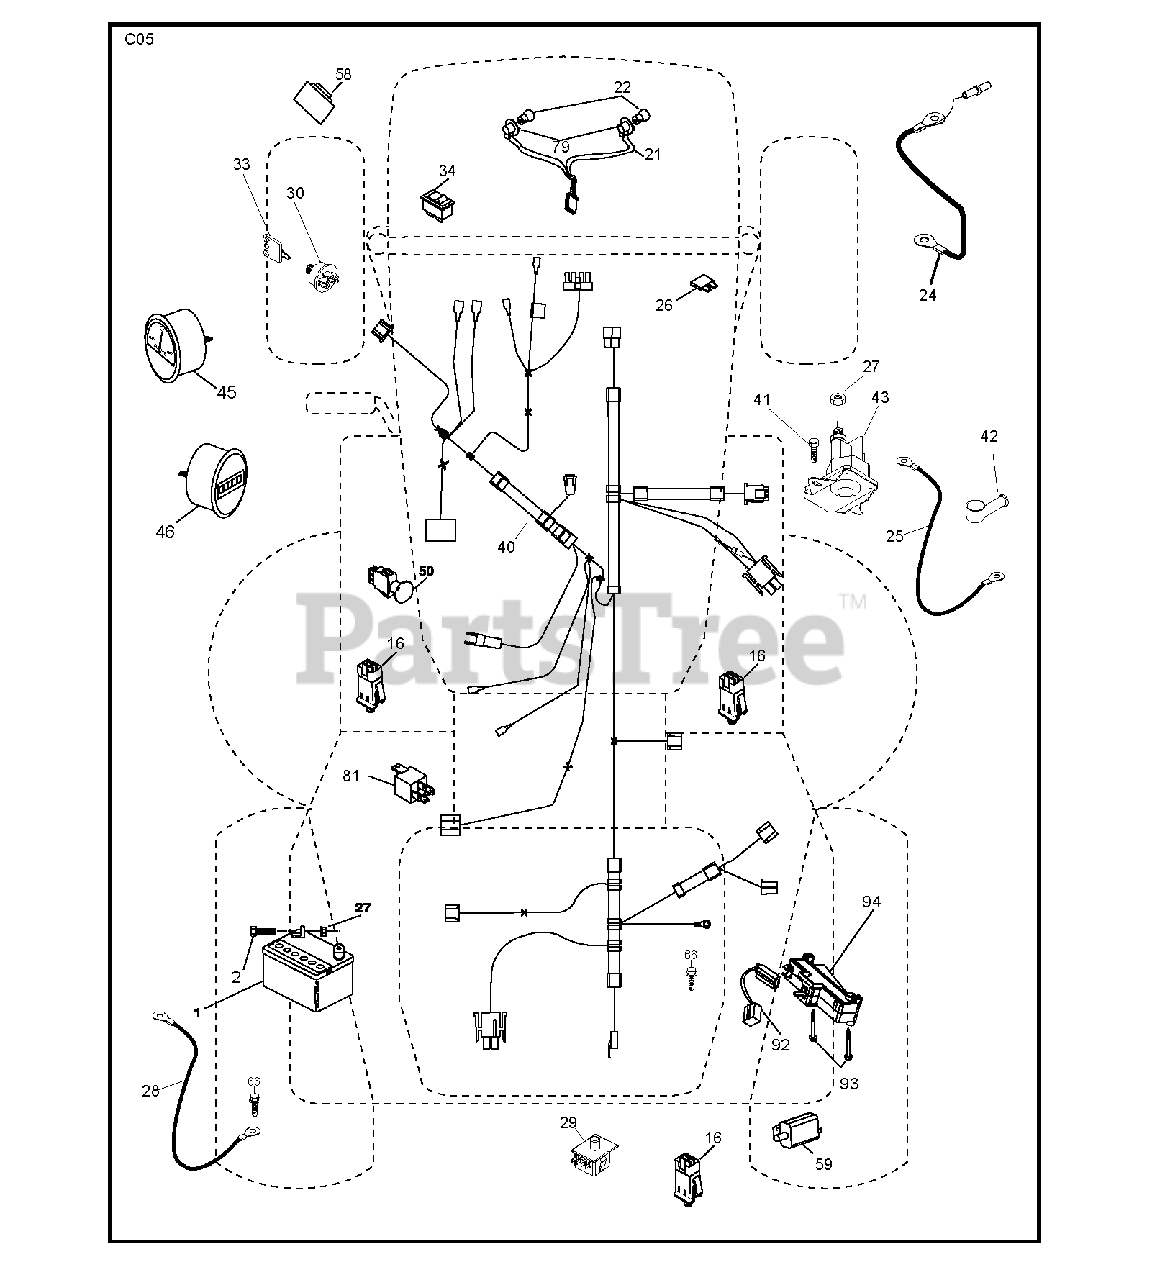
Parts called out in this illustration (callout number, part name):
1	REPL BY 532 12 38-99
16	SWITCH INTERLOOK PUSH-IN
21	HARNESS.W/LIGHT SOCKET
22	LIGHTBULB
24	CABLE BATTERY 6 GA. 11" RED
25	CABLE BATTERY
26	FUSE 20AMP
27	NUT
28	CABLE GROUND
29	SWITCH.SEAT.DP W/RAMPS
30	SWITCH.IGN.DELTA.W.LGH.ROS
33	KEY.CHAIN.BLISTER.PACK.GEN.INT
34	SWITCH LT
42	TERMINAL COVER
43	SOLENOID.W/BRASS.PLUNG
50	PTO SWITCH
58	BUZZER
79	BULB HOLDER ASM.
81	RELAY.ASSY.T
92	HARNESS.PIGTAIL.CONSLE
93	SCREW.PLASTITE
94	MODULE.REVERSE.ROS
